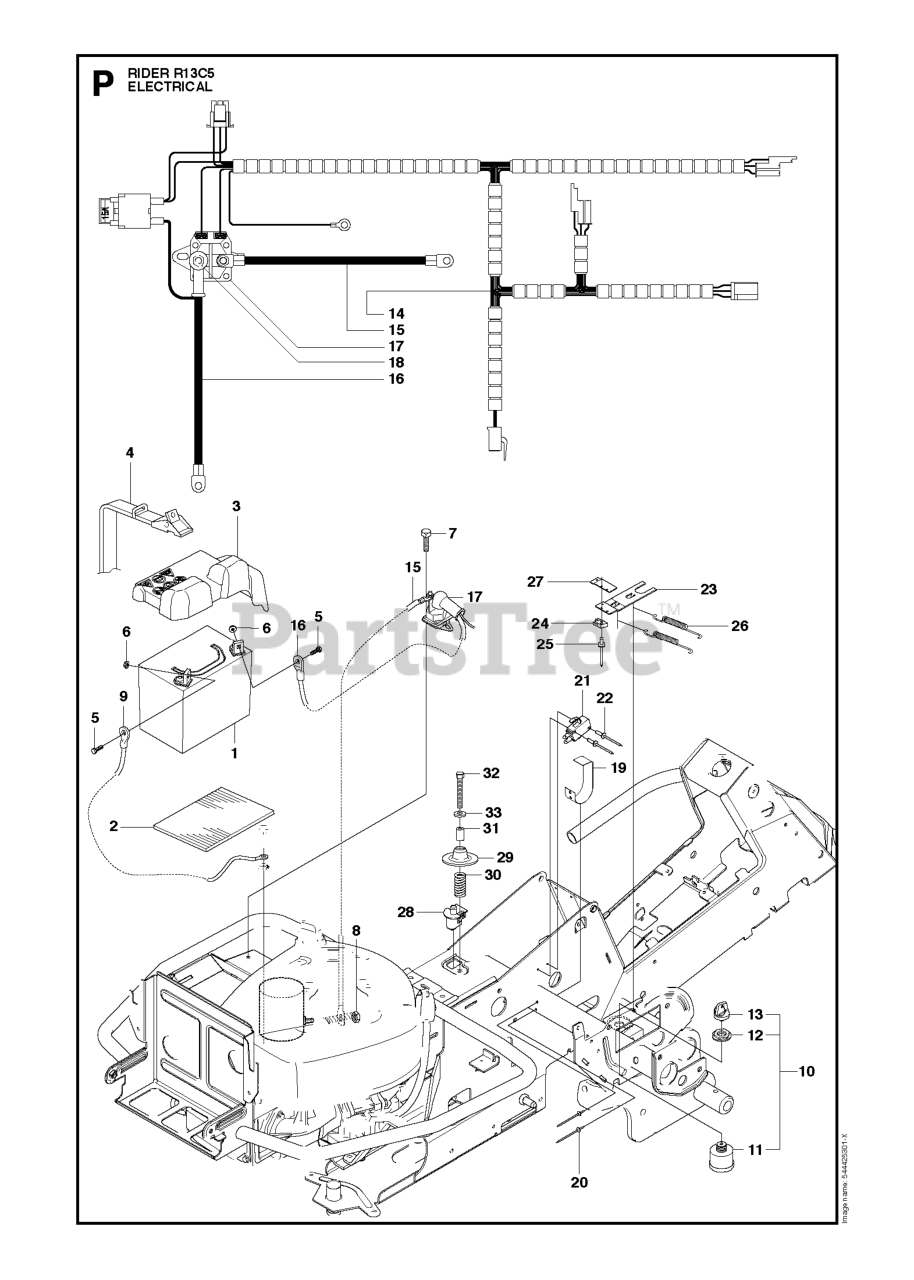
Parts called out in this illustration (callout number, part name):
5	SCREW EHHM
10	IGNITION SWITCH
11	IGNITION SWITCH
13	IGNITION KEY
24	%BRAKER
31	SPACER TUBE
32	SCREW
33	WASHER BRB 8.4X17
